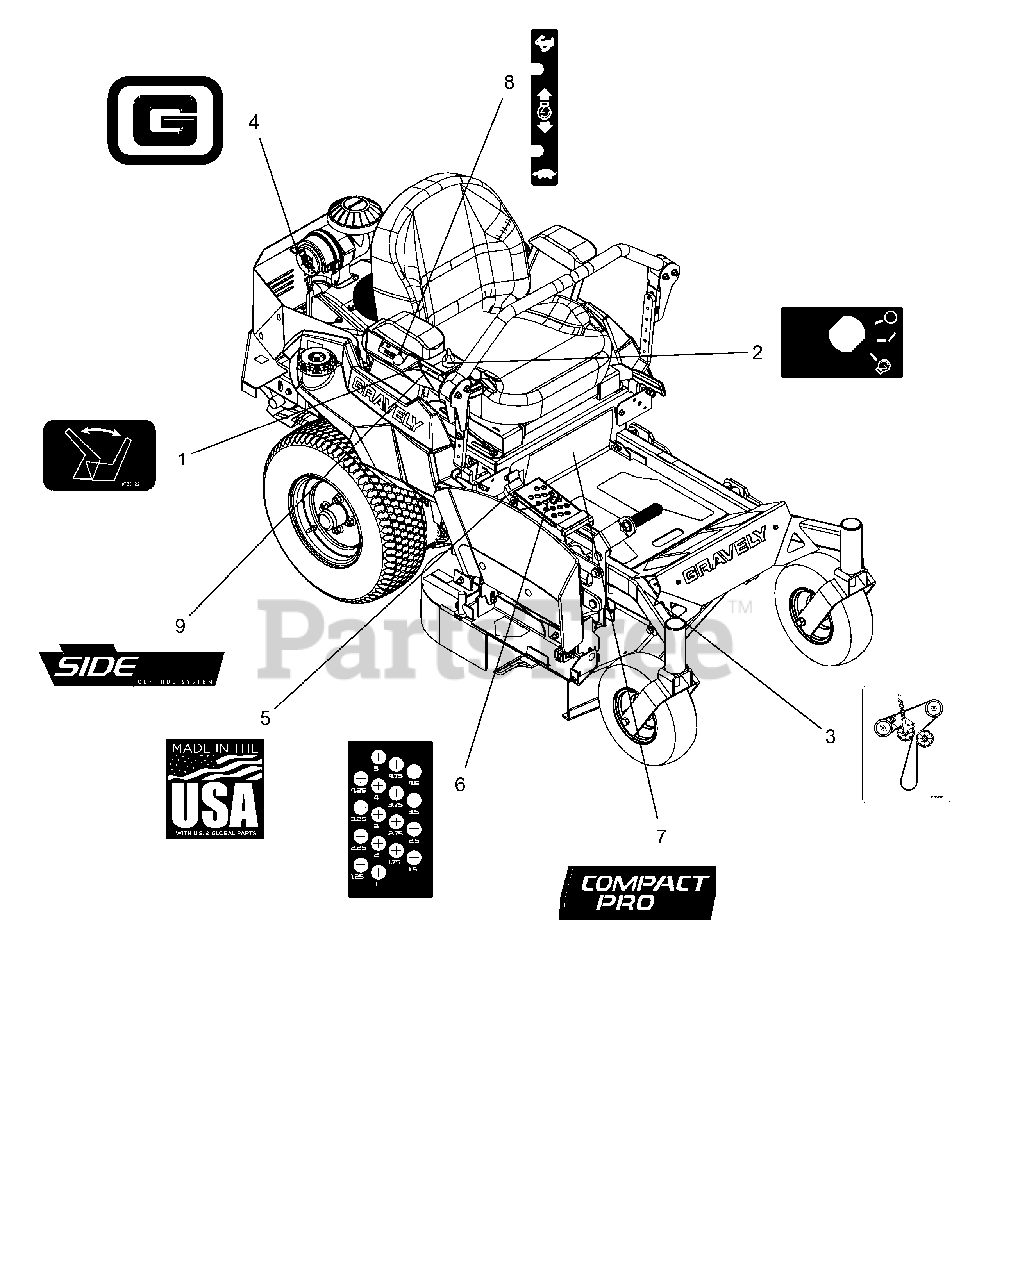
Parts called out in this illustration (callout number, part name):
1	DECAL - SEAT RELEASE
2	DECAL, KEY SWITCH
3	DECAL, 36 PW DECK BELT ROUTING
4	DECAL, GRAVELY BRAND
5	DECAL, MADE IN USA
6	DECAL, COMPACT PRO HOC
7	DECAL, COMPACT PRO 34"
8	DECAL, DASH - SPEED
9	DECAL, CONTROL COVER
